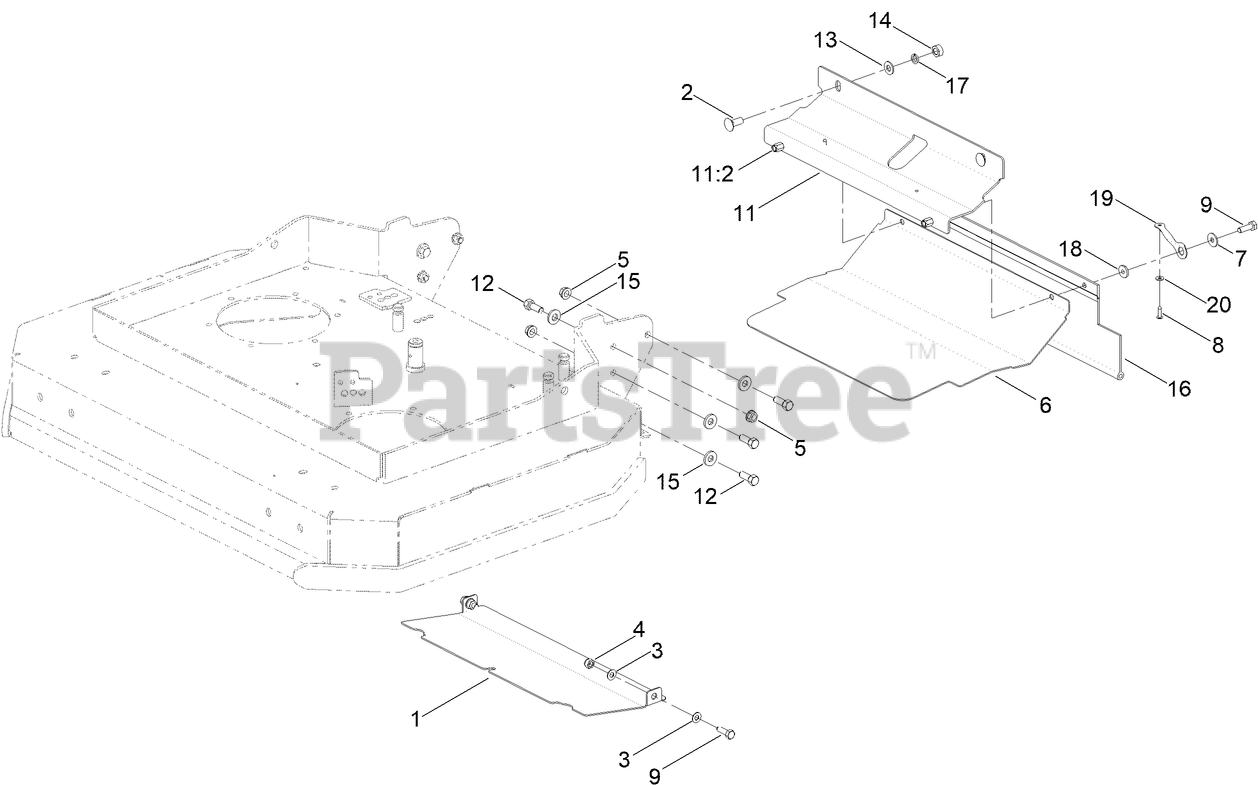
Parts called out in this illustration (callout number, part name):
1	GUARD-DISCHARGE, CENTER
2	BOLT-CARR
3	WASHER
4	NUT-HEX, NI
5	NUT-HHF, WHIZ
6	GUARD-UNDERSIDE
7	WASHER
8	RIVET
9	SCREW-HH
11	GUARD-DRIVE
11:2	NUT-RIVET
12	SCREW-HH
13	WASHER-PLAIN
15	WASHER-BELLEVILLE
16	SHIELD-DRAG
17	WASHER-LOCK
18	NUT-RETAINER
19	LANYARD-3 INCH
20	WASHER
